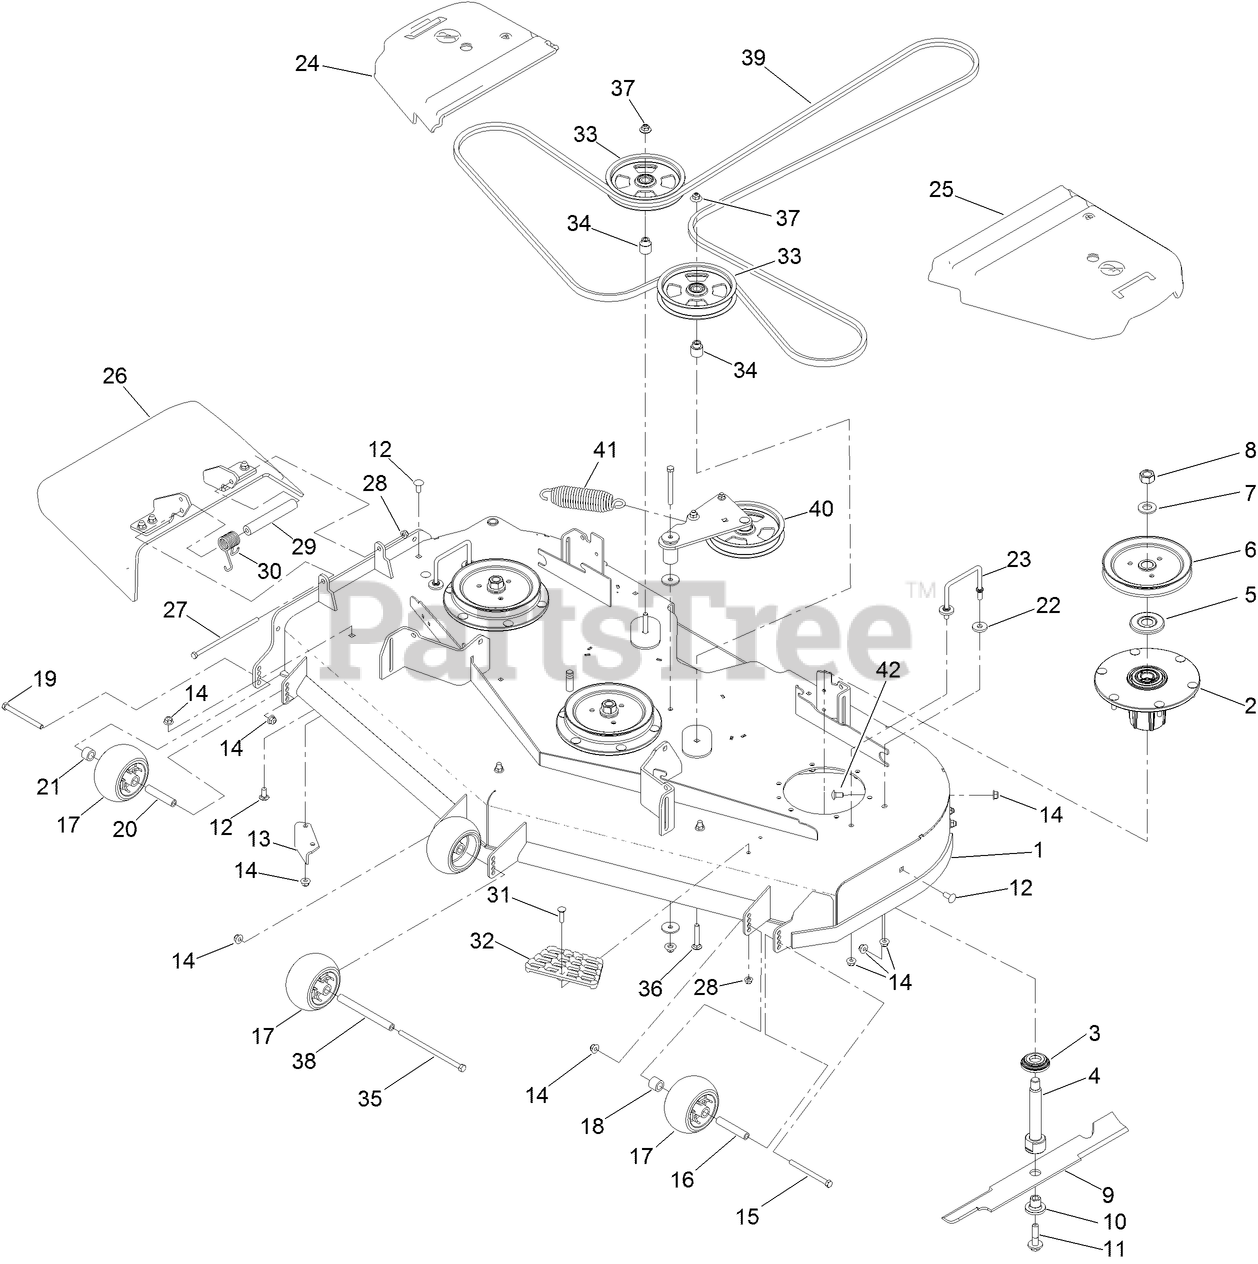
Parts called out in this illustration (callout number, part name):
1	DECK DECAL ASM
2	SPINDLE ASM
3	GUARD-BOTTOM
4	SHAFT-SPINDLE
5	GUARD-BEARING, TOP
6	SHEAVE-DRIVE, BLADE
7	WASHER
8	NUT-HEX
10	BUSHING-HEX
11	SCREW-SEMS
12	SCREW-CARR
13	BAFFLE-DISCHARGE
14	NUT-HF, NI
15	SCREW-HH
16	TUBE-SPANNER
17	ROLLER-SCALP, ANTI
18	TUBE-SPACER
19	SCREW-HH
20	TUBE-SHAFTING
21	TUBE-SPACER
22	WASHER
23	WIREFORM-COVER
24	COVER-BELT, RH
25	COVER-BELT, LH
26	RUBBER DEFLECTOR ASM
27	SCREW-HH
28	NUT-HF, NI
29	SPACER
30	SPRING-TORSION
31	SCREW-CARR
32	STEP-DECK
33	PULLEY-IDLER, FLAT
34	BUSHING, IDLER
35	SCREW-HH
36	SCREW-CARR
37	NUT-FLANGE, NI
38	SPACER-WHEEL
39	BELT-V
40	IDLER ARM ASM
41	SPRING-EXTENSION
42	SCREW-CARR
